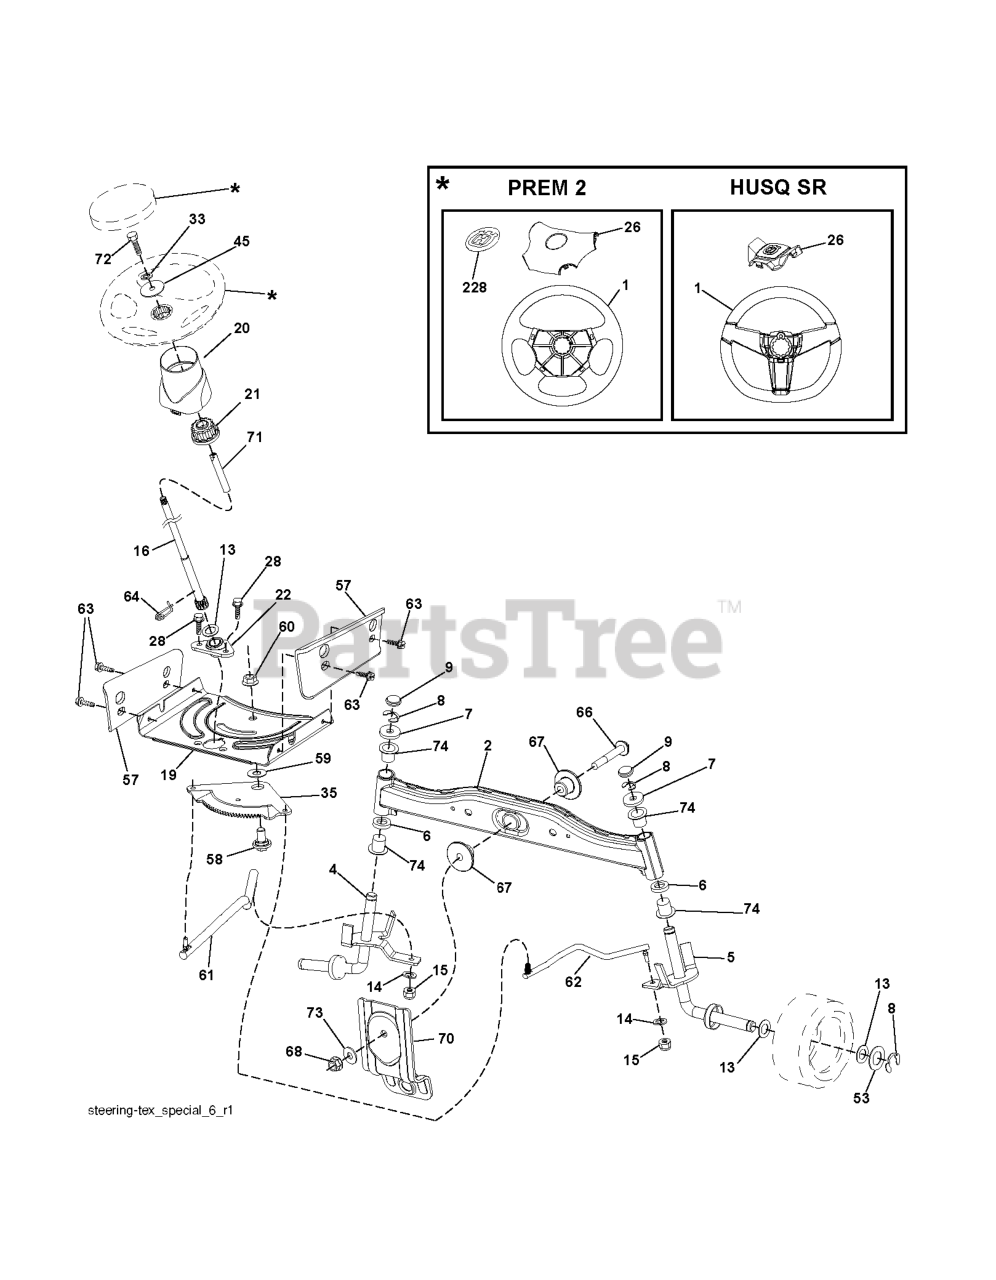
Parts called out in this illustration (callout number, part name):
1	RP WHEEL.STEER.HUSQ.PREM.OVMLD
2	AXLE.HALF.ASM.WELDED
4	SPINDLE.WELDED.LH.15"TEX
5	SPINDLE.WELDED.RH.15"T
6	THRUST WASHER
9	CAP.SPINDLE.BLACK
14	WASHER, LOCK 3/8
15	NUT CROWNLOCK 3/8-24
16	SHAFT STEERING
19	PLATE.STEER.DDL.NLT/NG
20	BOOT, STEERING
21	ADAPTER, WHEEL STNG..
22	BUSHING.ASM.STEERING.A
26	RP INSERT.CAP.WHL.STRG.HUSQ.
28	SCREW, 3/8-16X3/4
33	WASHER.LOCK.HVY.HLCL.SPR.5/16
35	GEAR.SECTOR.PLATE.DDL.
45	WASHER.11/32
53	WASHER.HARDENED
57	BRACKET.UPSTOP.TEX
58	BOLT.SHOULDER.SECTOR.P
59	WASHER.THURST.SECTOR.S
60	NUT FLANGE LOCK 5/8-11
61	DRAGLINK.LH.BALLSTUD.D
62	DRAGLINK.RH.BALLSTUD.D
63	SCREW
64	RETAINER.CLIP.SPRING.S
66	BOLT HEX FGHD 7/16-14 X 3 SERR
67	BUSHING.PM.FRONT AXLE
68	NUT.LOCK.FLANGE.7/16
70	BRKT.DECK.SUSPENSION.F
71	SHAFT EXTENSION STEERING
72	BOLT YT
73	WASHER.1.5X.505X.118
74	BRNG T
228	DECAL.WHEEL.STRG.LGN.H
